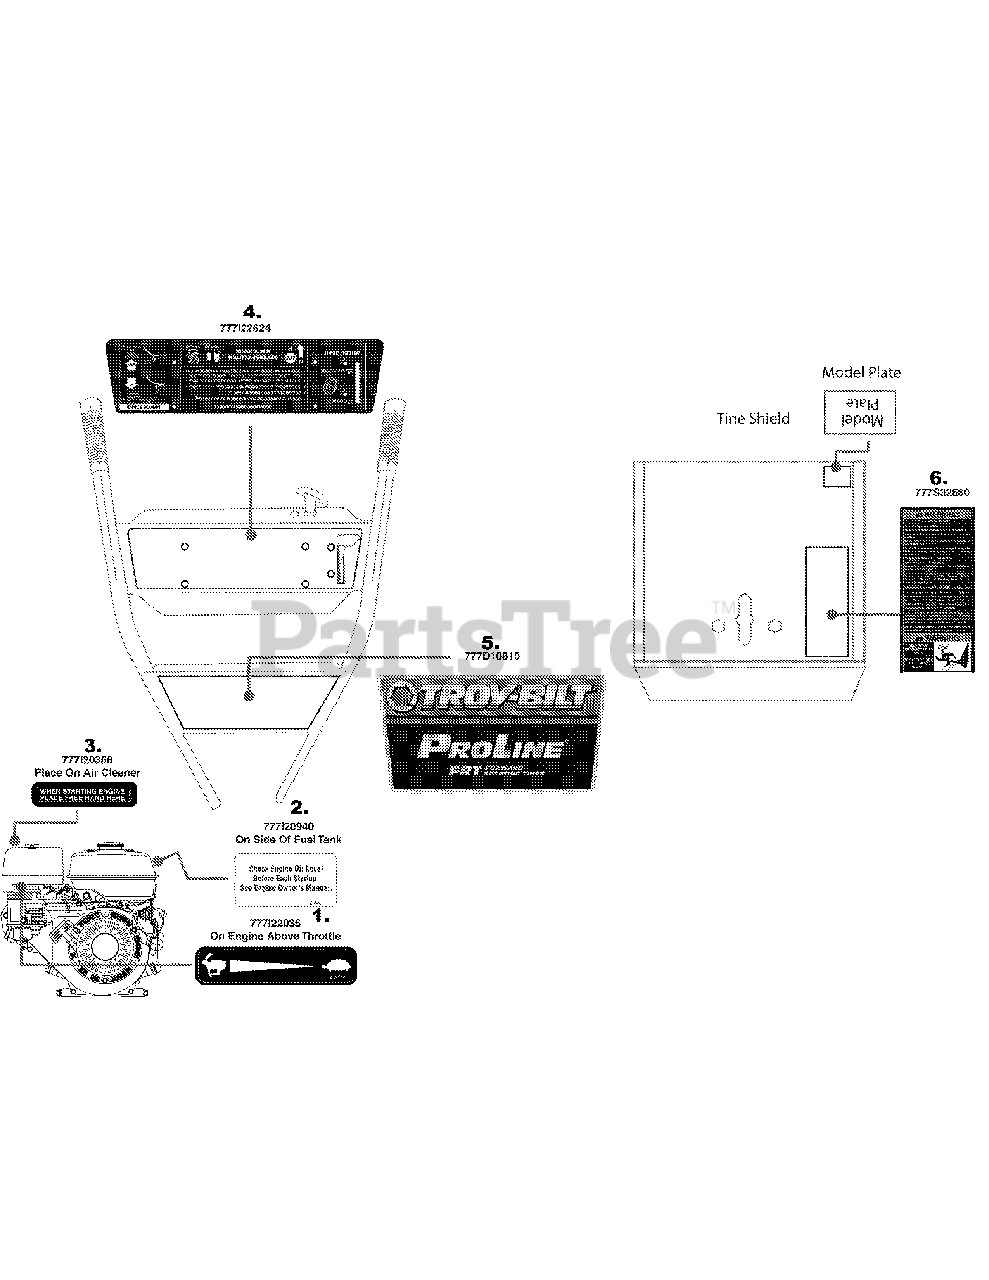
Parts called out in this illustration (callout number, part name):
1	LABEL-ENGINE
2	LABEL-CHECK ENGINE
3	LABEL-PLACE HAND HERE
4	LABEL:TILLER HANDLE:660
5	LABEL-TILLER HANDLE PANEL
6	LABEL:TILLER TINE SHIELD
